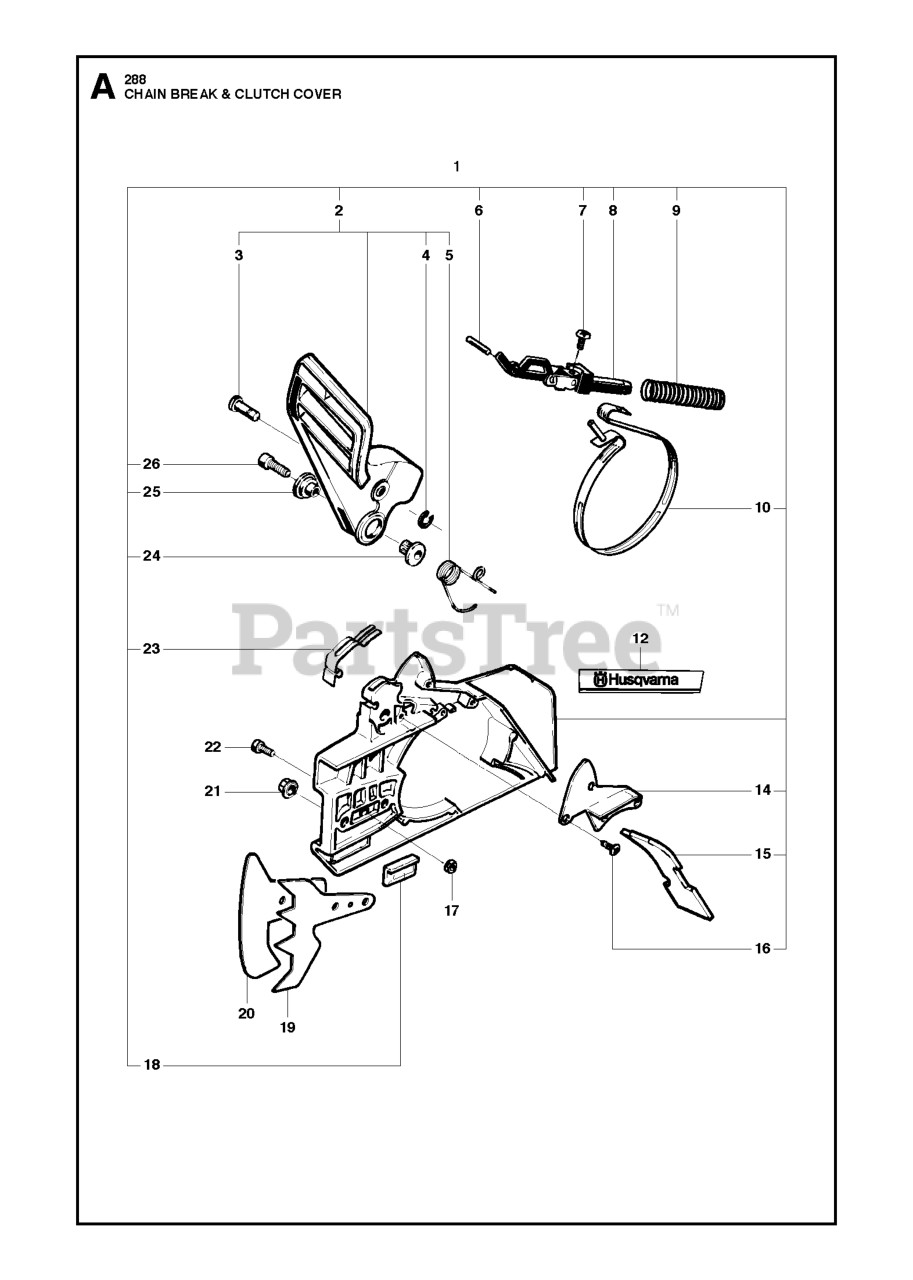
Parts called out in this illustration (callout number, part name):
1	CHAINBRAKE
6	HARDENED PIN
8	KNEE-JOINT
9	BRAKE SPRING
10	BRAKE BAND
18	CHAIN GUIDE
19	FELLING DOG
20	Felling Dog
21	NUT M8 FLANGE
22	SCREW MC6S 5X12
24	PIVOT SLEEVE L
25	PIVOT SLEEVE R
